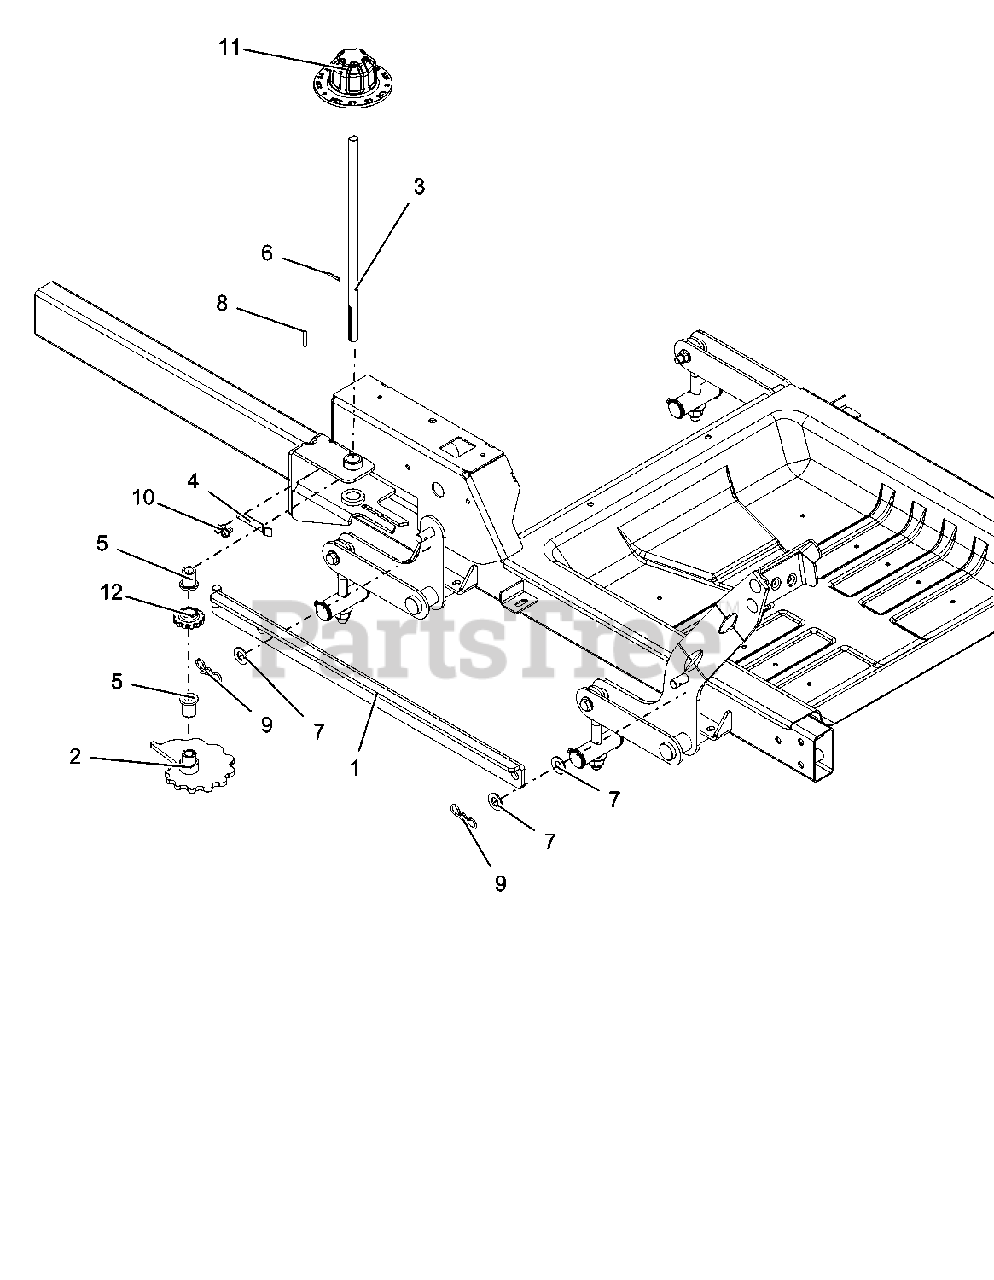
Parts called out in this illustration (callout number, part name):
1	WLDMT, HOC LINK
2	WLDMT, HOC CAM
3	SHAFT, HOC CAM
4	ARM, HOC DETENT
5	BSHG-FLG, .503X.750X.875X1.00
6	PIN-ROLL .125X1.00
7	WSHR-FL-NYL .518X1.000X.080
8	KEY, 1/8 X 1/8 X 1.0
9	PIN,BOW TIE LOCKING .091X1.875
10	@SCR-TAP .25-20X.37 HWH YWZ TR
11	KNOB, HOC
12	GEAR, HOC INDEX
